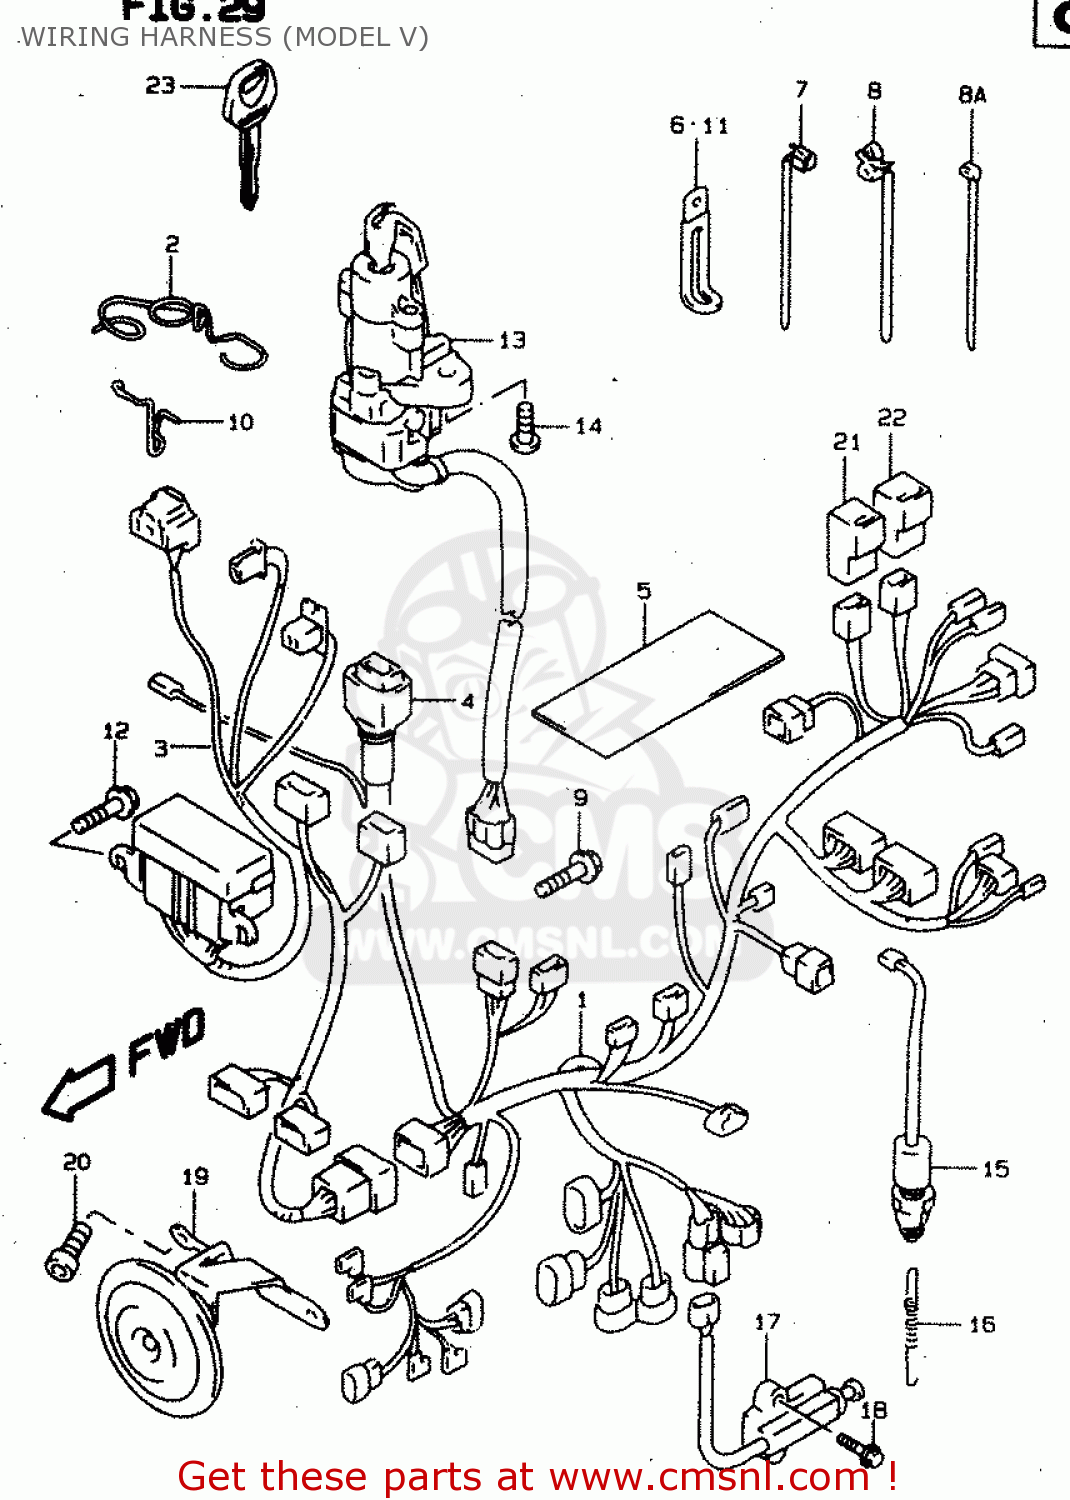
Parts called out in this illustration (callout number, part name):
1	HARNESS,WIRING NO.1
2	GUIDE,WIRING HARNESS
3	HARNESS,WIRING NO.2
4	COVER,SPEEDOMETER COUPLER
5	PROTECTOR,WIRING HARNESS
6	CLAMP(L:65)
7	CLAMP
8	CLAMP
8A	CLAMP(L:145)
9	BOLT
10	STOPPER,FUSE BOX
11	CLAMP(L:80)
12	SCREW 6X12
13	LOCK ASSY,STEERING
14	BOLT(8X20)
15	SWITCH ASSY,STOP LAMP
16	SPRING
17	SWITCH ASSY,SIDE STAND WARNING
18	BOLT
19	HORN ASSY
20	BOLT
21	RELAY ASSY
22	RELAY ASSY
23	KEY,BLANK
